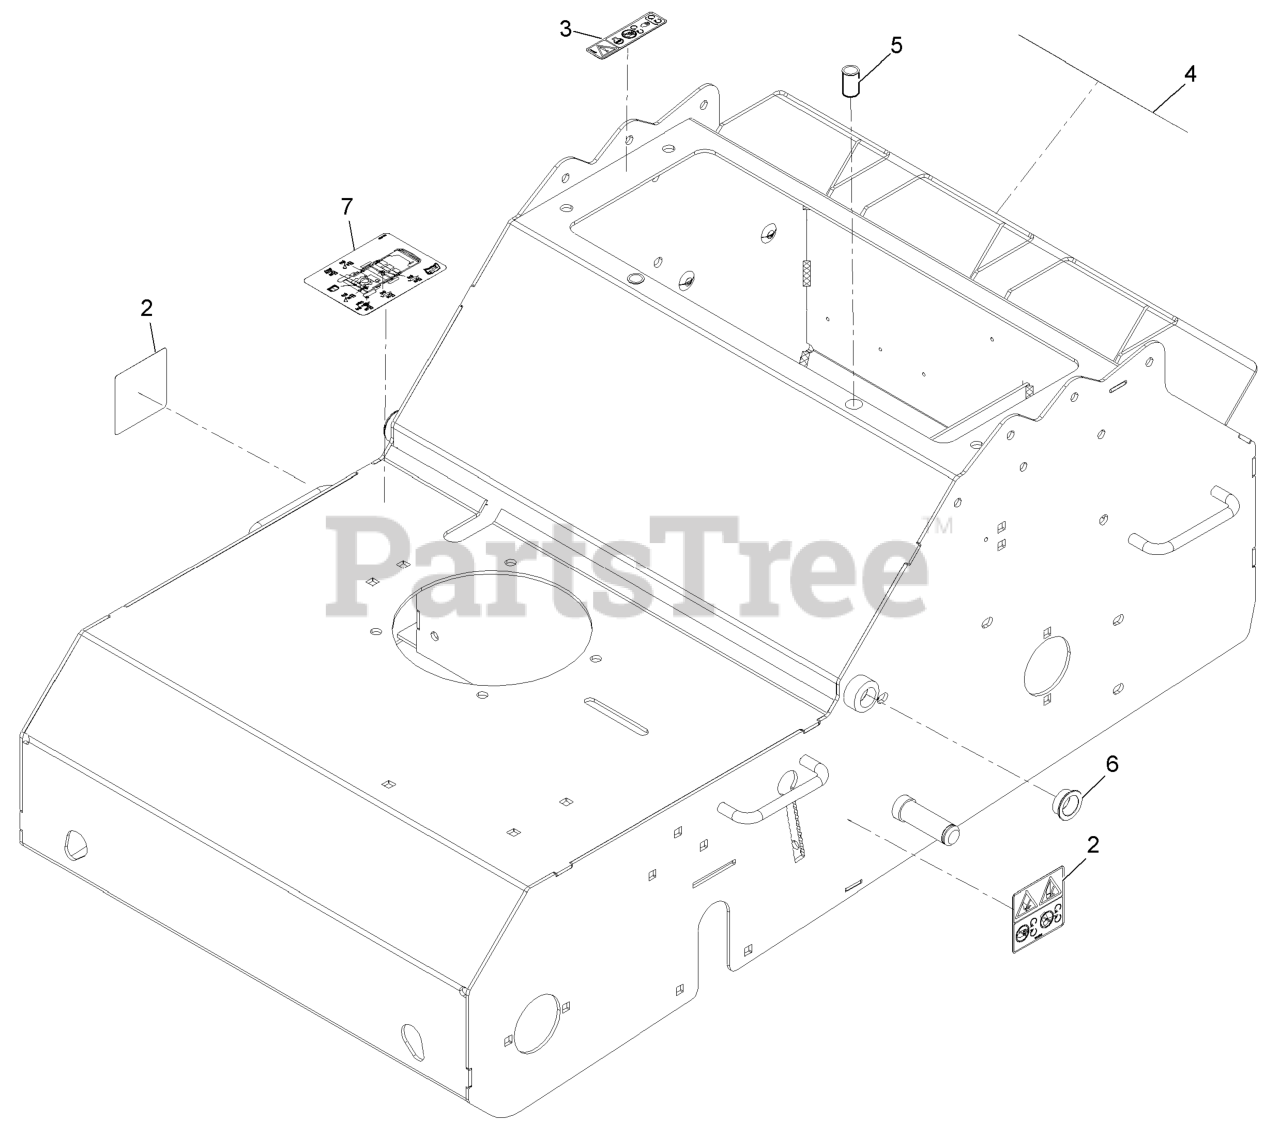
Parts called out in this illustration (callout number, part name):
2	DECAL-WARNING
3	DECAL-DANGER
4	Decal-Warning
5	NUT-CLINCH
6	BUSHING-BRONZE
7	Decal-Service Aid
